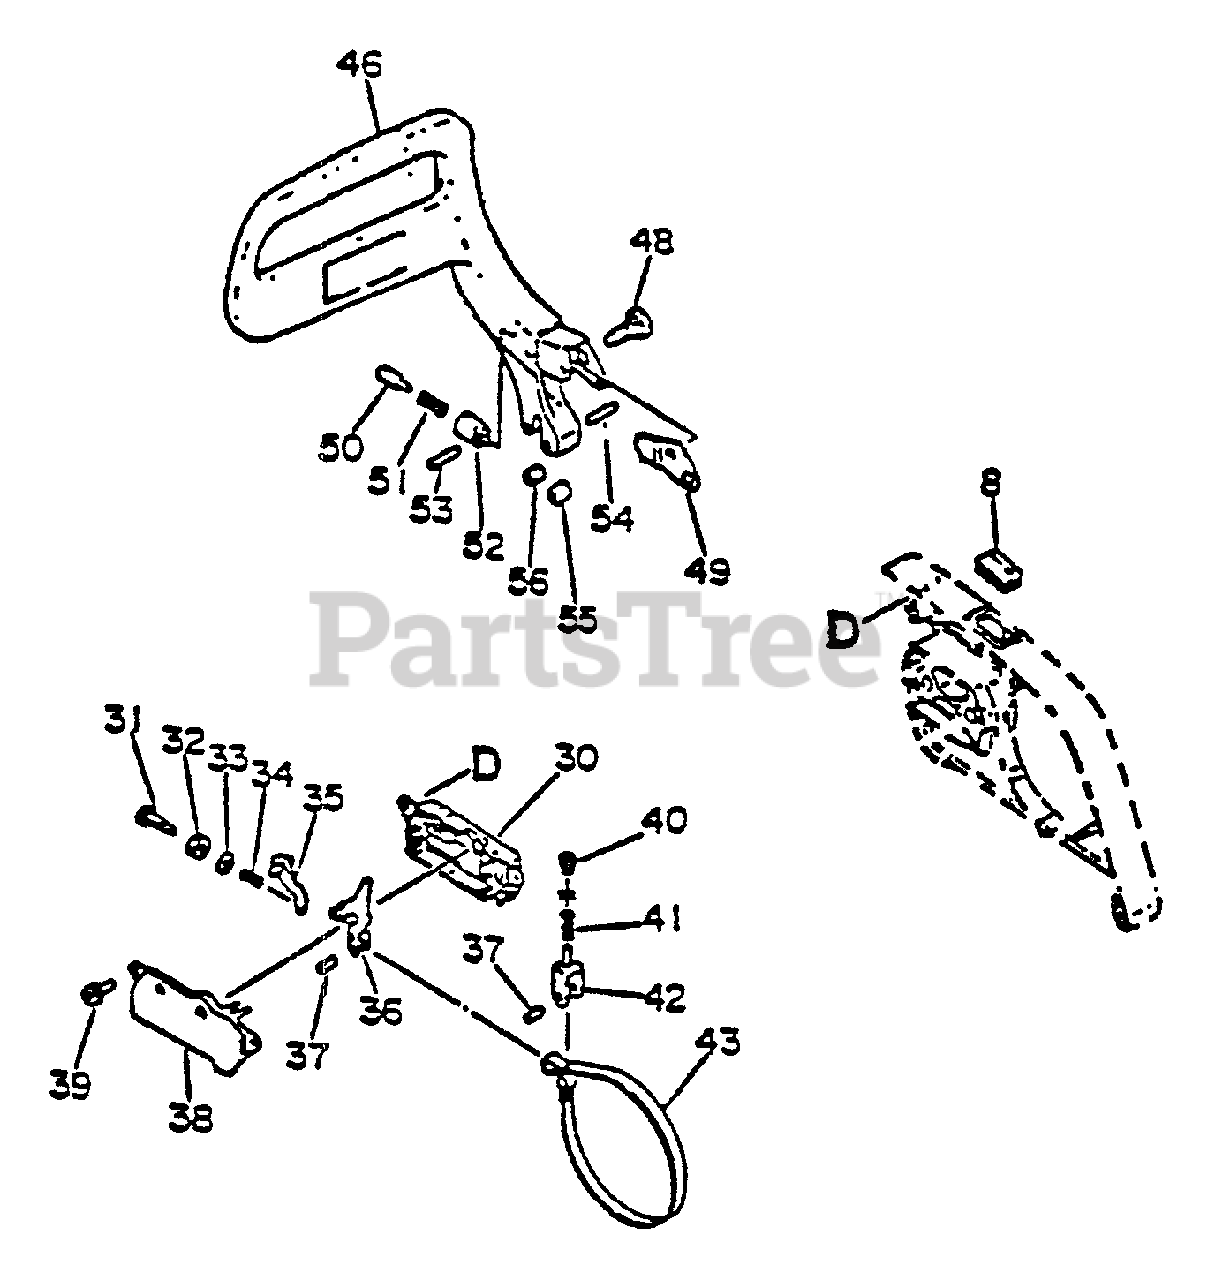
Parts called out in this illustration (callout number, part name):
8	CHAIN BRAKE ASSY
30	COVER, BRAKE
34	SPRING, BRAKE
35	STOPPER, BRAKE
36	LEVER, BRAKE
37	PIN - SPRING -- 4X10
38	COVER, BRAKE
39	SCREW - 4X10
42	ADJUSTER, BRAKE BAND
43	BAND, BRAKE
46	BRAKE LEVER ASSY
55	SPACER
56	SPACER
